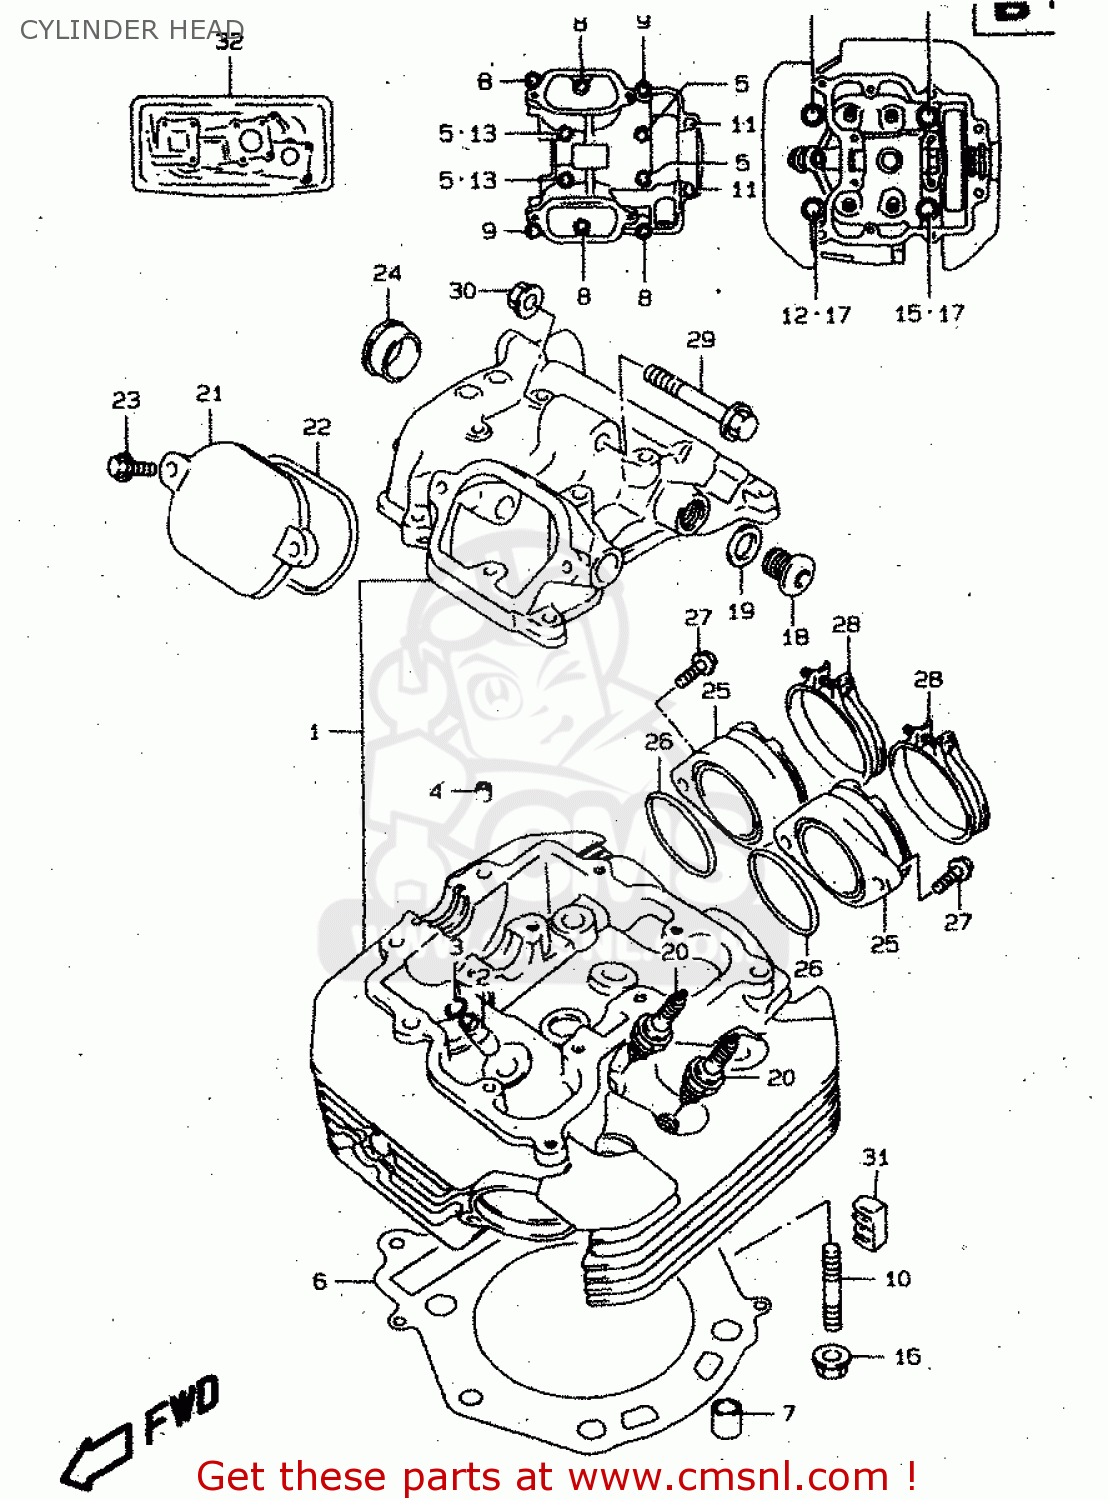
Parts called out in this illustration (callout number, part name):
1	HEAD ASSY,CYLINDER
2	GUIDE,VALVE
3	RING,SNAP
4	PIN(6.2X8X11)
5	BOLT(6X55)
6	GASKET,CYLINDER HEAD
7	PIN
8	BOLT
9	BOLT
10	BOLT,STUD
11	BOLT(6X115)
12	BOLT(10X180)
13	GASKET(5.8X13X1.2) (NAS)
14	BOLT(10X190)
15	BOLT(10X200)
16	NUT
17	GASKET(10.5X22X2) (NAS)
18	PLUG,14X12
19	GASKET(13.8X18.8X4.8) (NAS)
20	PLUG,SPARK(CR10E)
21	CAP,INSPECTION
22	O RING,INSPECTION CAP
23	BOLT
24	PLUG,OD:30
25	PIPE ASSY,INTAKE
26	O RING(D:2.4,ID:39.7)
27	SCREW
28	CLAMP
29	BOLT(8X60)
30	NUT
31	PAD,CYLINDER HEAD RUBBER
32	GASKET SET
